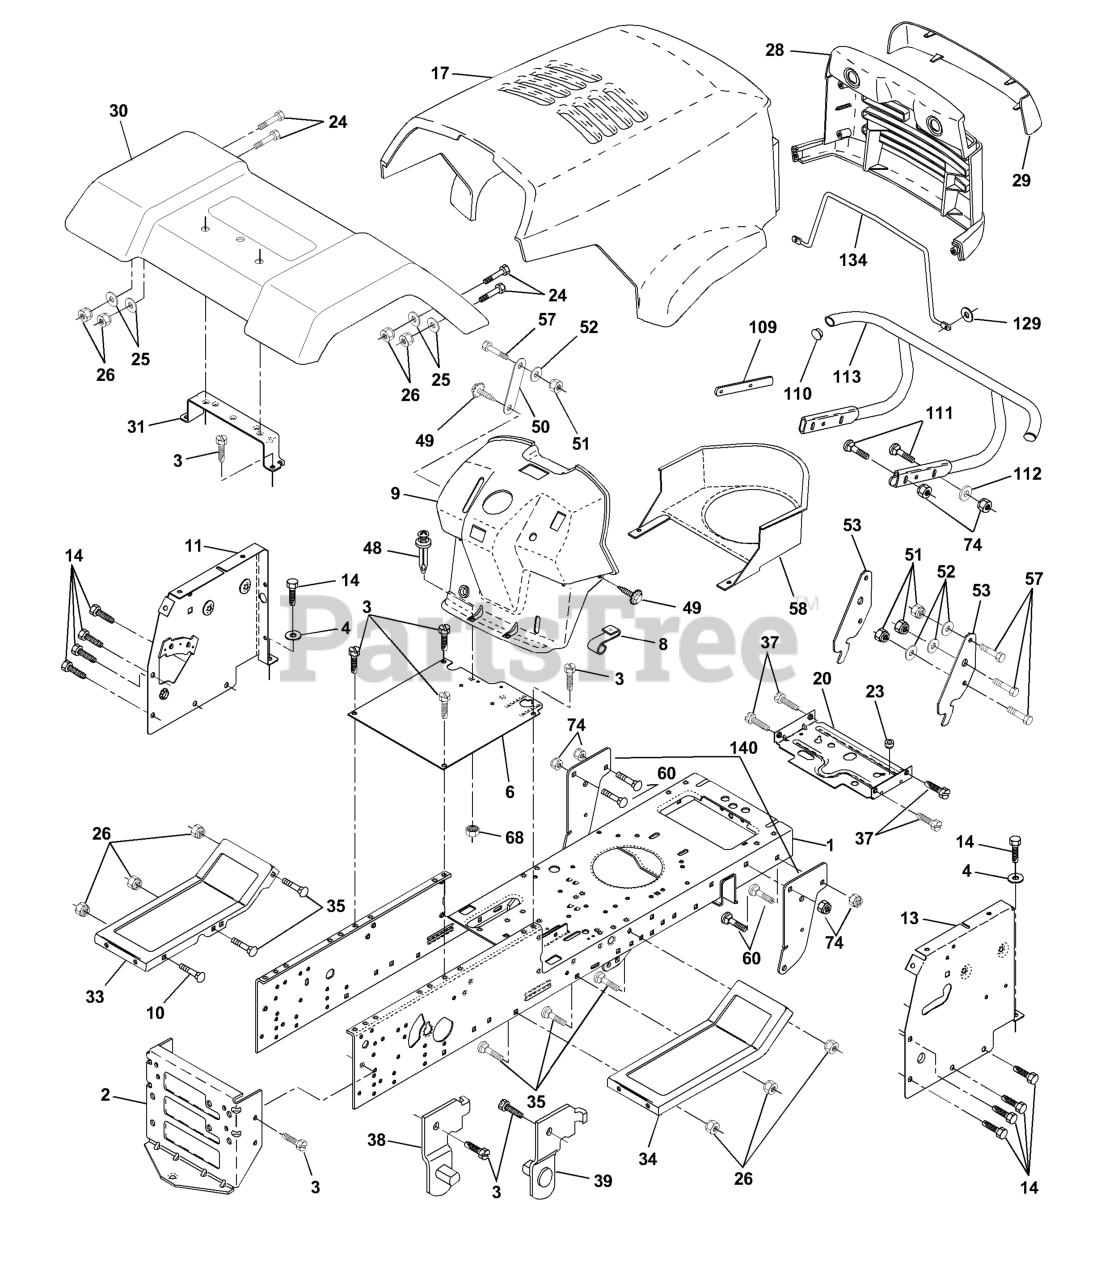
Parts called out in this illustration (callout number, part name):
1	CHASSIS WLD MT 11G
2	STRETCH DRAWBAR
3	SCREW
4	Washer 13/32 x 3/4 x 16 Ga.
6	SADDLE LT FENDER
8	CLIP,INSULATOR
9	DASH PLATE
10	BOLT D
11	PANEL PNT DASH LH
13	PANEL
14	SCREW LT
17	HOOD LT/PL HUSQVARNA
20	PLATE MTG BATTERY FUEL TAND
23	BUSHING.SNAP.NYL.BLK.
24	BOLT
25	WASHER
26	NUT
28	GRILLE LT/PL HUSQVARNA
29	LENS LT/PL HUSQVARNA
30	FENDER
31	BRACKET FENDER
33	FOOT REST LH
34	FOOTREST RH
35	BOLT
37	Screw Thdrol 5/16-18 X 1/2
38	BRACKET LH PIVOT
39	BRACKET RH PIVOT
48	RIVET PUSH
49	SCREW HEX CRT
51	LOCKNUT.NYLOC.1/4-20
52	WASHER
53	BRACKET PNT PICK OFF LT/PL
57	BOLT
58	AIR DUCT P/L/LT
60	Bolt Rdhd Sqnk 3/8-16 Unc x 3/4
68	NUT
109	BRACKET BUMPER
110	PLUG PLASTIC
111	BOLT.3/8-14X1.25
112	WASHER
113	BUMPER ASM
129	WASHER
134	ROD SUPPORT HOOD LT/PL HUSQ
140	BRACKET CHASSIS FRONT
